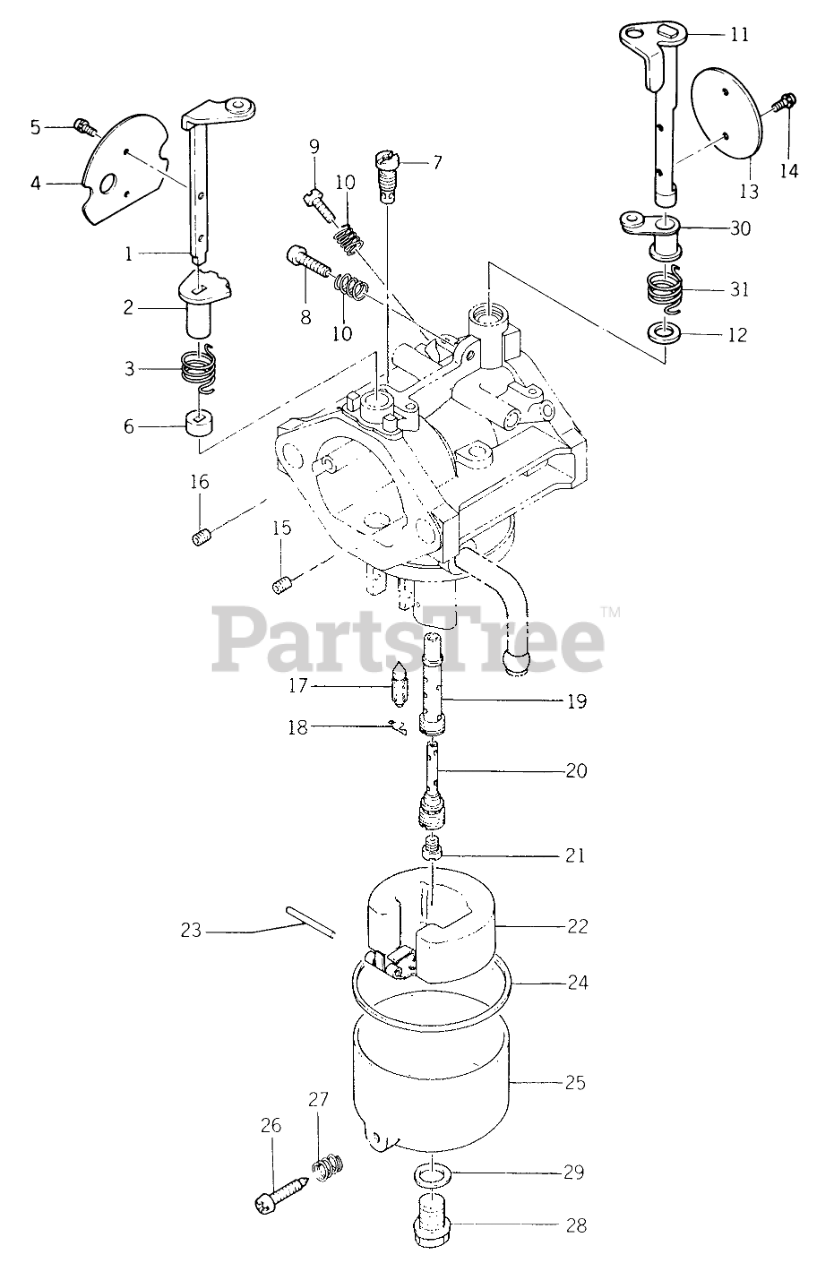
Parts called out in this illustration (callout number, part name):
1	SHAFT, choke
4	VALVE, choke
6	Ring
7	JET, pilot (No.50)
8	SCREW (4x12)
9	SCREW, adjuster
11	SHAFT, throttle
12	Seal
13	VALVE, throttle (No.110)
15	Jet-Air, #1.7
16	JET, pilot air (No.1.1)
17	Valve-Float
19	NOZZLE, main (No.12C)
20	PIPE, bleed
21	JET, main (=97.5)
22	FLOAT
25	Float Chamber Assy (includes items 18 & 19).
26	Screw
27	SPRING
29	WASHER
